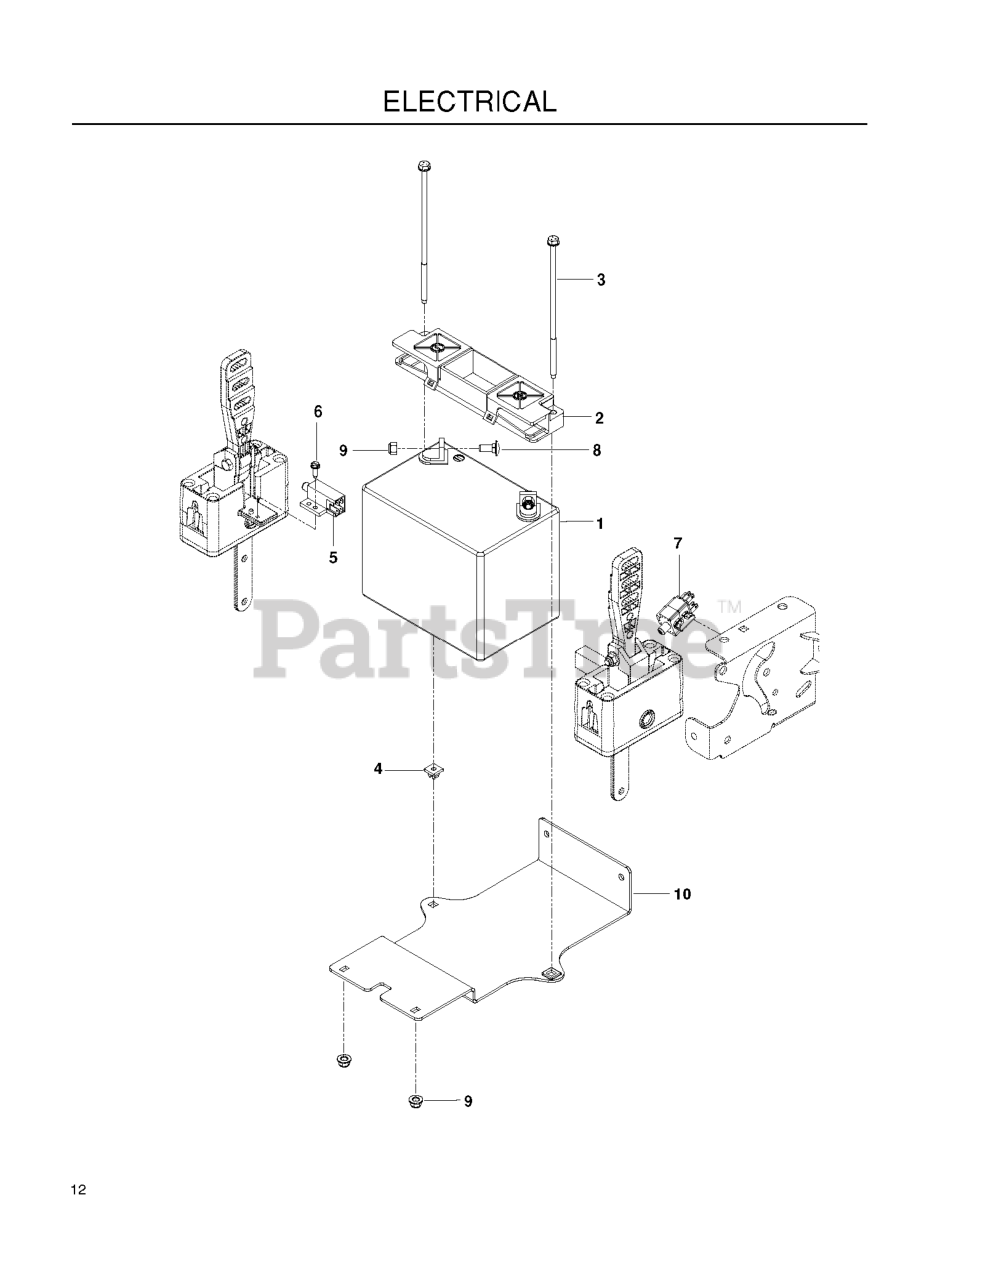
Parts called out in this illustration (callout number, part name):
1	BATTERY, 12 V 330 AMP
2	BATTERY HOLD DOWN
3	BOLT - 1/4-20 X 7.5
4	PUSH NUT-NYLON
5	SWITCH, INTERLOCK
6	SCREW #10 X 1/2 SELF TAPPING
7	SWITCH, BRAKE 3P
8	BOLT 5/16C X 3/4" CARRIAGE
9	5/16-18 NYLOC FLANGE NUT
10	PLATE, BATTERY, BLACK
